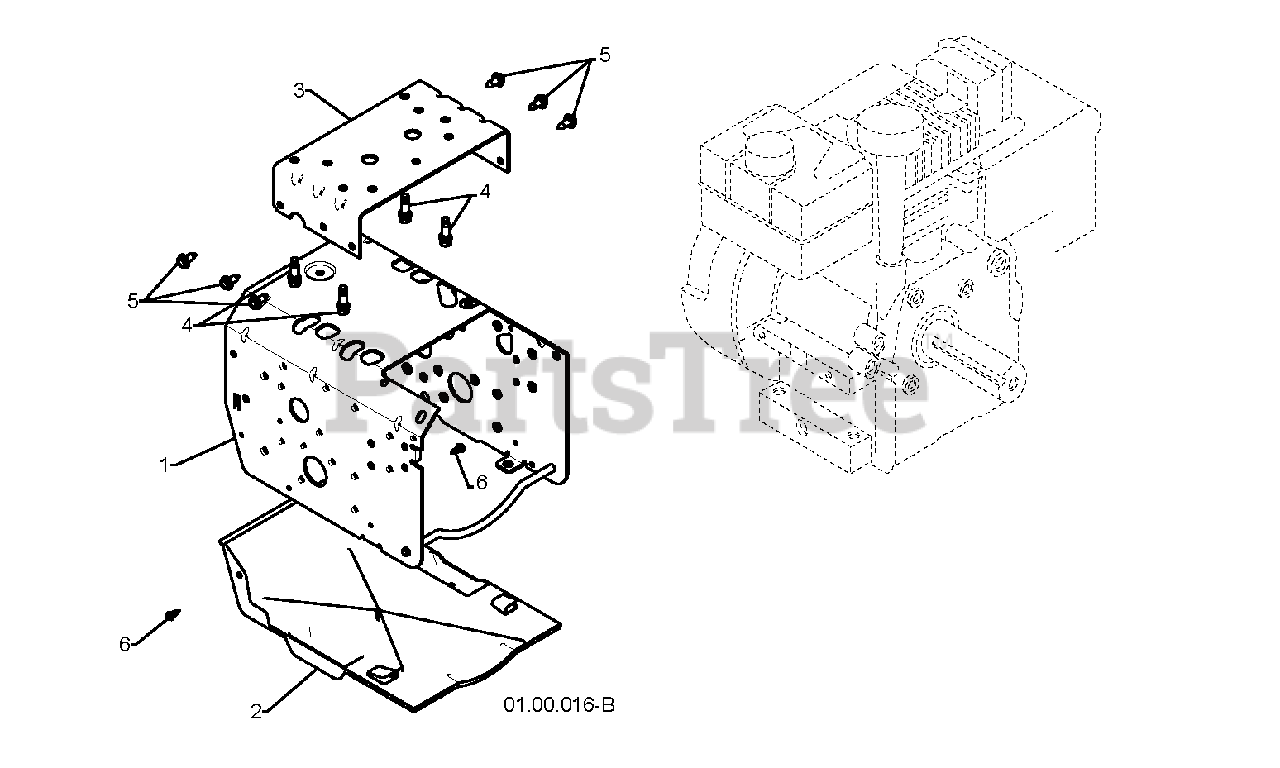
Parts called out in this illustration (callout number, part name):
2	PAN.BOTTOM.PLASTIC
4	BOLT 3/8-16X1-1/8
5	BOLT.HEX.HD.WASHER.5/16-18X.75
6	SCREW, HEX HEAD, TAPPING
